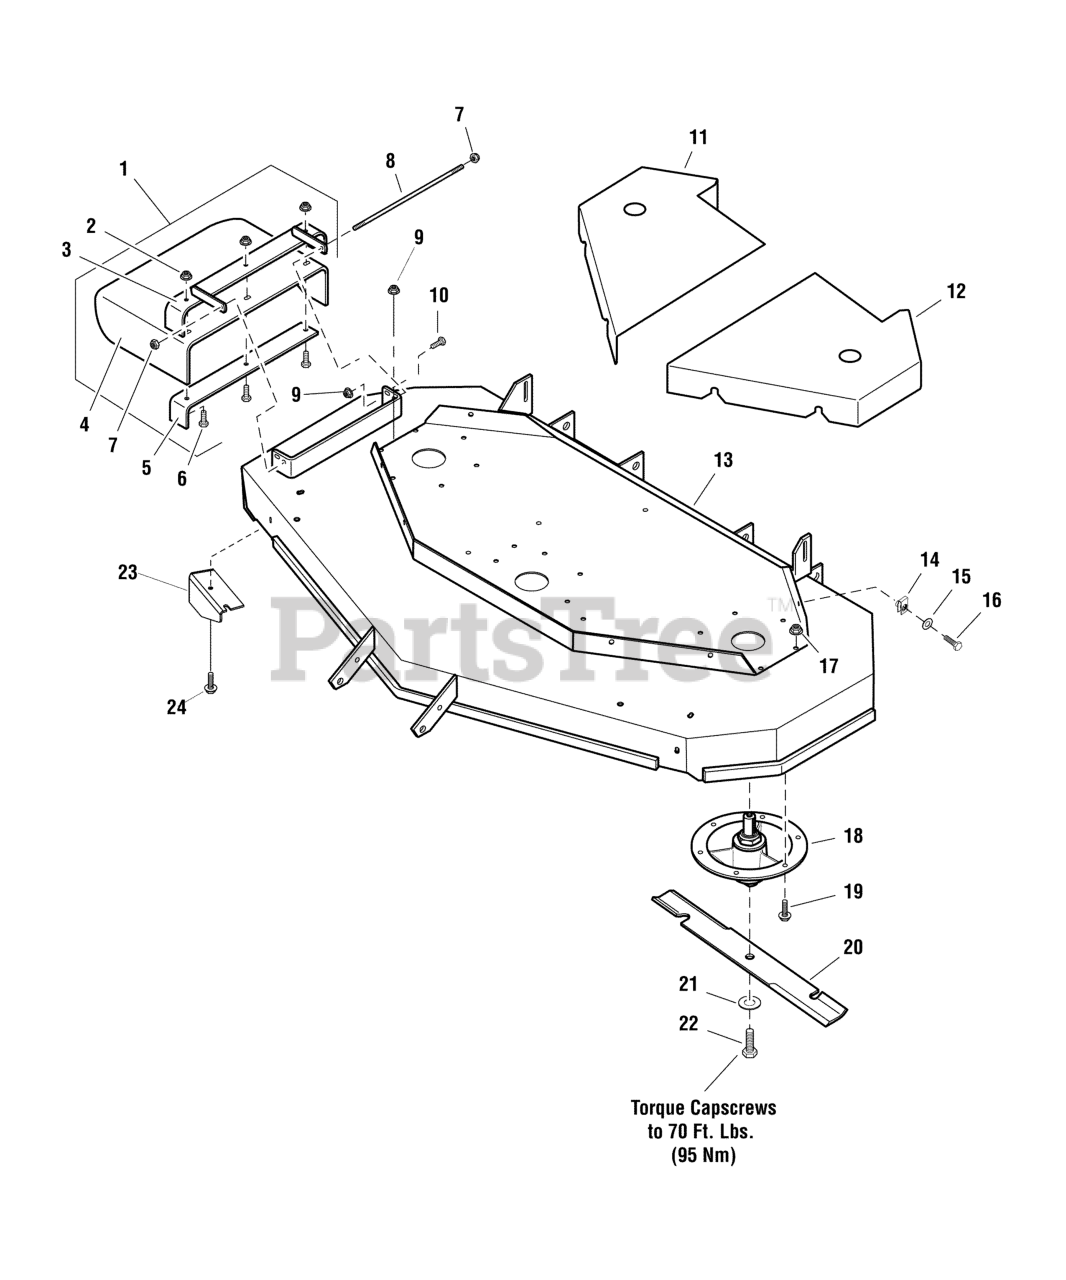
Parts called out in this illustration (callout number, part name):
1	PURCHASE INDIVIDUAL REPLACEMENT PARTS
2	NUT, 3/8-16 HEX NYLOCK FLANGE
3	WELD, FRAME, CHUTE, 61 - RED
4	CHUTE, DISCHARGE, RUBBER, 61/72, BENT
5	SUPPORT, DISCHARGE CHUTE - BLK
6	BOLT, 3/8-16 X 1-1/4" GD5 CZ
7	NUT, 5/16-24 HEX NYLON LOCK
8	ROD, MOUNT CHUTE, 61"
9	NUT, 5/16-18 HEX NYLOCK FLANGE
10	BOLT, 5/16-18 X 3/4 GD5
11	GUARD 61" - RH
12	GUARD 61" - LH
13	DECK SHELL W/DECALS, 61", IS3100Z
14	BODY CLIP, 5/16-18-7GA MATERIAL
15	WASHER, 5/16" SAE
16	BOLT, 5/16-18 X 3/4 GD5
17	NUT, 3/8-16 HEX NYLOCK FLANGE
18	SPINDLE ASSEMBLY
19	BOLT, 3/8-16 X 1-1/4", FLANGE
20	BLADE, 21"
21	WASHER, 5/8" GRADE 8, YZ
22	BOLT, 5/8-11 X 1-3/4 GD8
23	PLATE, DEFLECTOR - BLK
24	BOLT, 5/16-18 X 3/4, CARRIAGE
